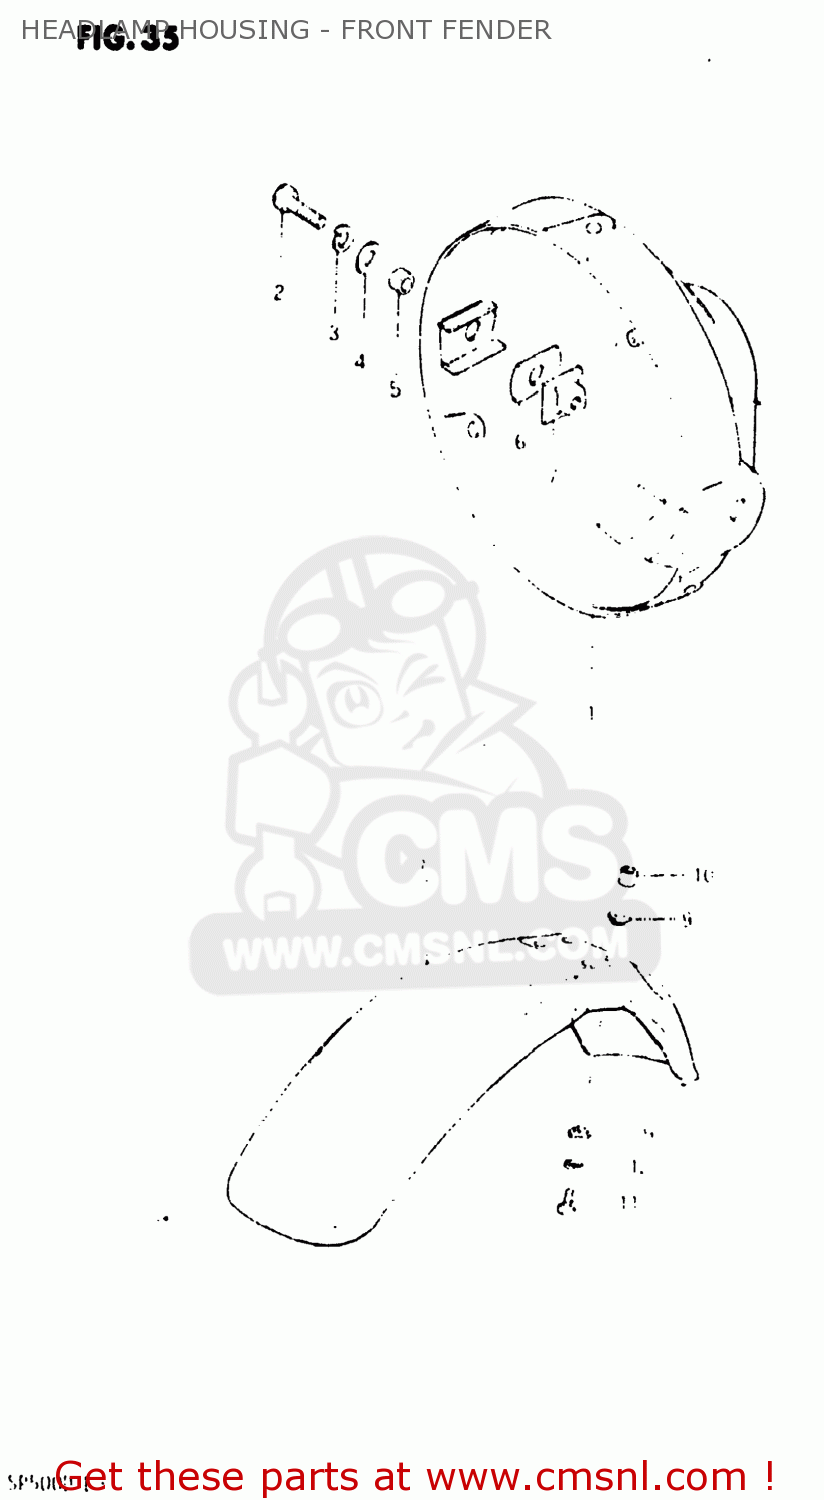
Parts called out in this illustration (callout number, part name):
1	HOUSING,HEADLAMP
2	BOLT
3	LOCK WASHER
4	WASHER
5	SPACER (8.8X12X7)
6	CUSHION
7	PLATE,HEADLAMP HOUSING
8	FENDER,FRONT
9	WASHER
10	SPACER (6.8X10X27.4)
11	BOLT
12	LOCK WASHER
